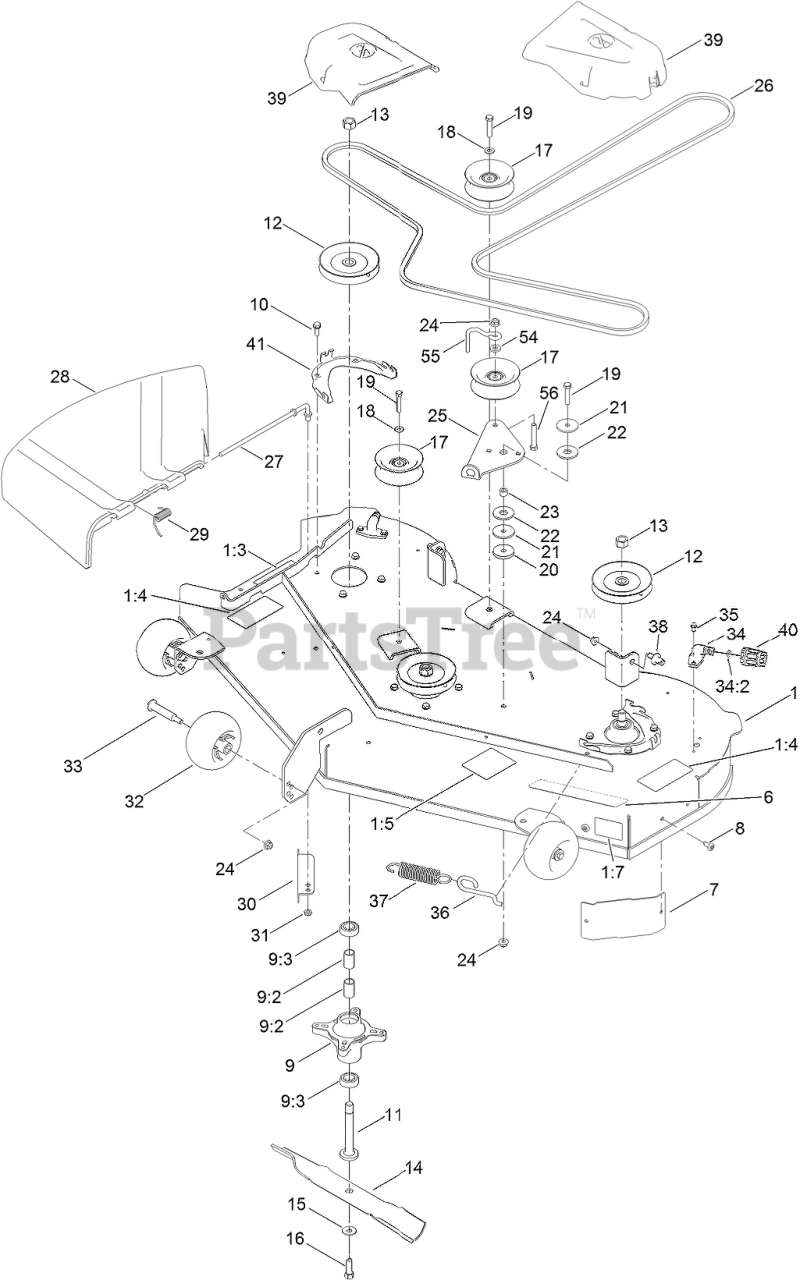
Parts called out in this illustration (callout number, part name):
1	50 INCH DECK AND DECAL ASM
1:3	DECAL-DANGER
1:4	DECAL-DANGER, DECK
1:5	DECAL-ROUTING, BELT
1:7	DECAL-SCALP, ANTI
6	DECAL - DECK
7	BAFFLE-CORNER
9	SPINDLE ASM
9:2	SPACER
9:3	BEARING-BALL
10	SCREW-TAPTITE
11	SHAFT-SPINDLE
12	PULLEY
13	NUT-HEX
14	BLADE-HI LIFT
15	WASHER-BELLEVILLE
16	SCREW-HH
17	PULLEY-IDLER, FLAT
18	WASHER-FLAT
19	SCREW-HH
20	WASHER-PLAIN
21	WASHER-REBOUND
22	WASHER-FRICTION, COMPOSITE
23	SPACER
24	NUT-HF, NI
25	ARM-IDLER
26	V-BELT
27	ROD-PIVOT
28	DEFLECTOR-DISCHARGE
29	SPRING-TORSION
30	BAFFLE-CUTOFF
32	ROLLER-SCALP, ANTI
33	BOLT-SHOULDER
34	FITTING-WASHOUT
34:2	O-RING
35	SCREW-HWH
36	HOOK-RETURN SPRING
37	SPRING-EXTENSION
38	PIN-DECK
39	COVER-BELT
40	CONNECTOR-HOSE
41	BRACKET-COVER, BELT
54	SPACER-HUB, BLOWER
55	BELT GUIDE - IDLER
56	SCREW-HH
